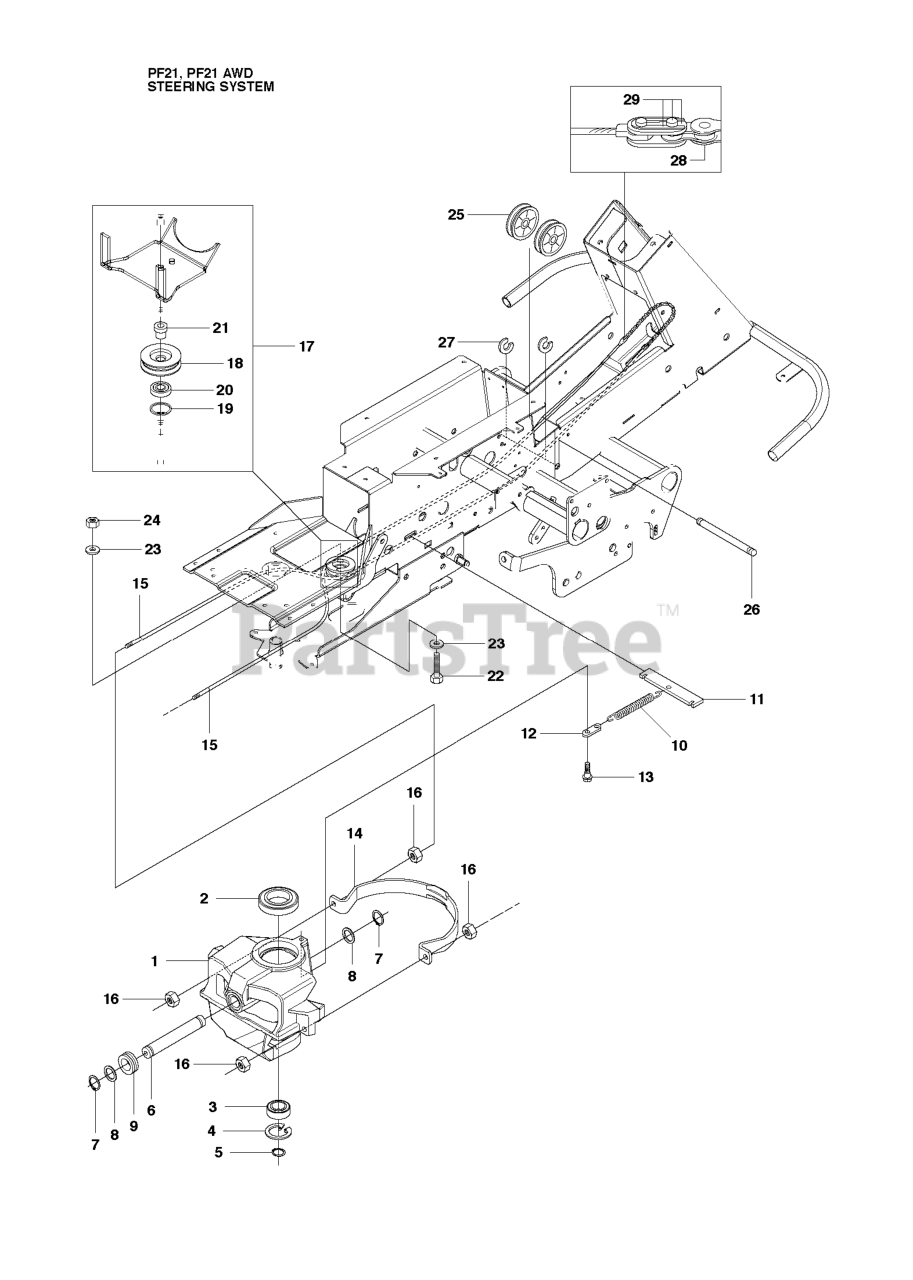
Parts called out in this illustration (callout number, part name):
2	BALL BEARING 6010 2RS1
3	Ball Bearing 6005-2rs
4	CIRCLIP SGH 47
5	RETAINING RING SGA 25
7	RETAINING RING SGA 25
11	SPRING BRACKET
14	WIRE GUIDE
15	WIRE ASSY
16	NUT
19	CIRCLIP SGH 47
20	BALL-BEARING 6204-2RS
22	REPL BY 725 25 00-71
24	NUT
26	SHAFT
27	RETAINING RING
28	STEERING CHAIN
